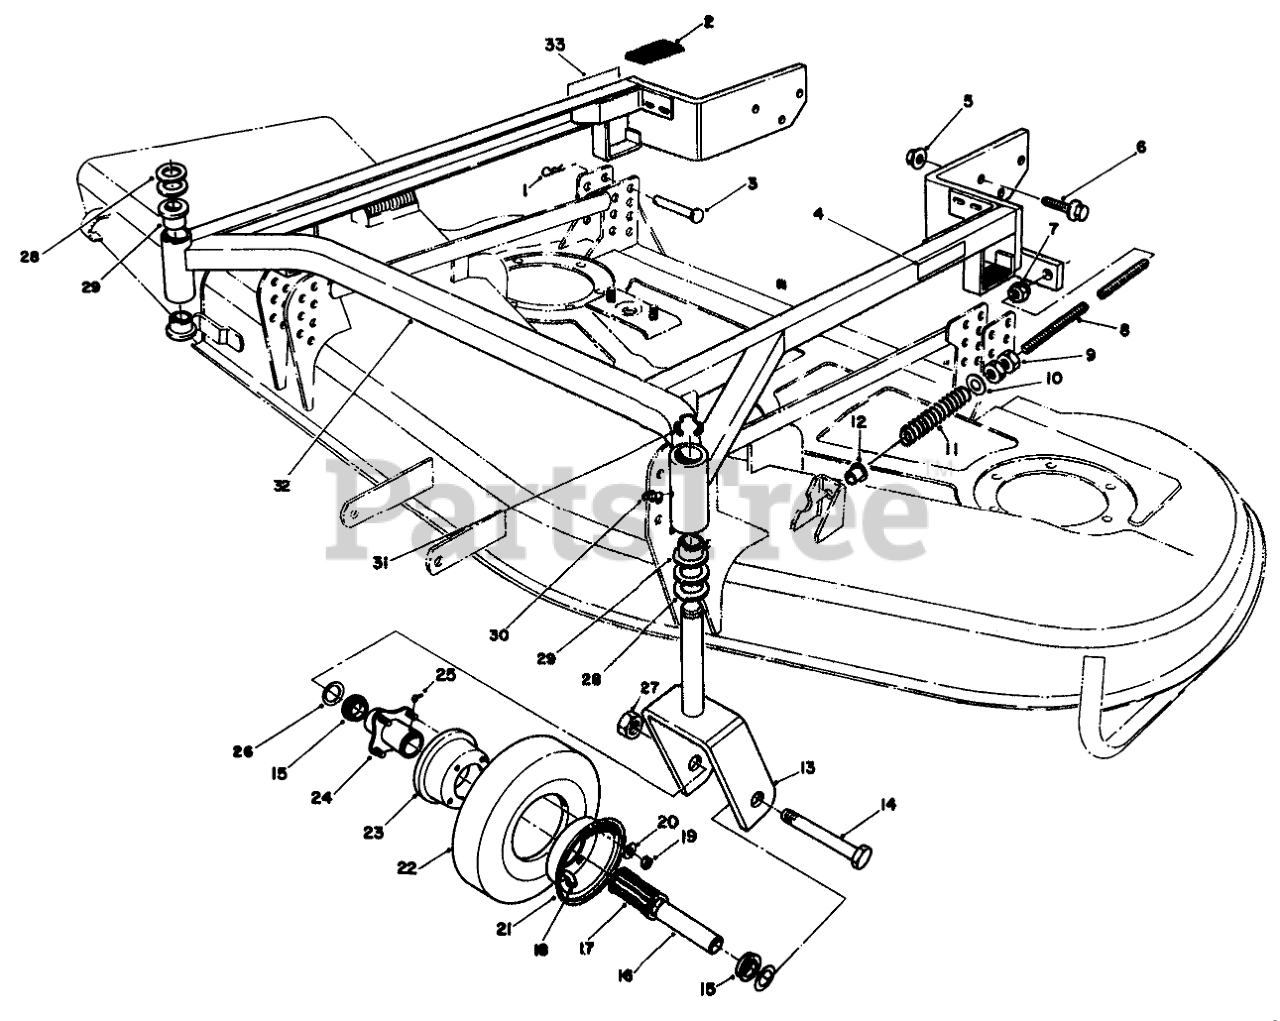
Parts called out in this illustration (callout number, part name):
1	PIN-HAIR
2	CUSHION-RUBBER
3	PIN-CLEVIS
4	DECAL-HOC, LH
5	NUT-HF
6	SCREW-HHF
7	NUT-LOCK, NI
8	SHAFT-ADJUSTING
9	NUT-JAM
10	WASHER
11	SPRING
12	BUSHING-FLANGE
13	Castor Fork
14	SCREW-HH
15	BEARING-OUTSIDE
16	SPANNER-TIRE
17	BEARING-ROLLER
18	TUBE-INNER (W/VALVE)
19	NUT-HEX
20	WASHER-LOCK
21	MALE WHEEL HALF
23	FEMALE WHEEL HALF
24	HUB-CENTER
25	FITTING-GREASE
26	WASHER-FLAT
27	NUT-HEX
28	WASHER-THRUST
29	Bushing
30	FITTING-GREASE
31	RING-RETAINING
32	Frame-Carrier (Incl. Ref. #30)
33	DECAL-HOC, RH
